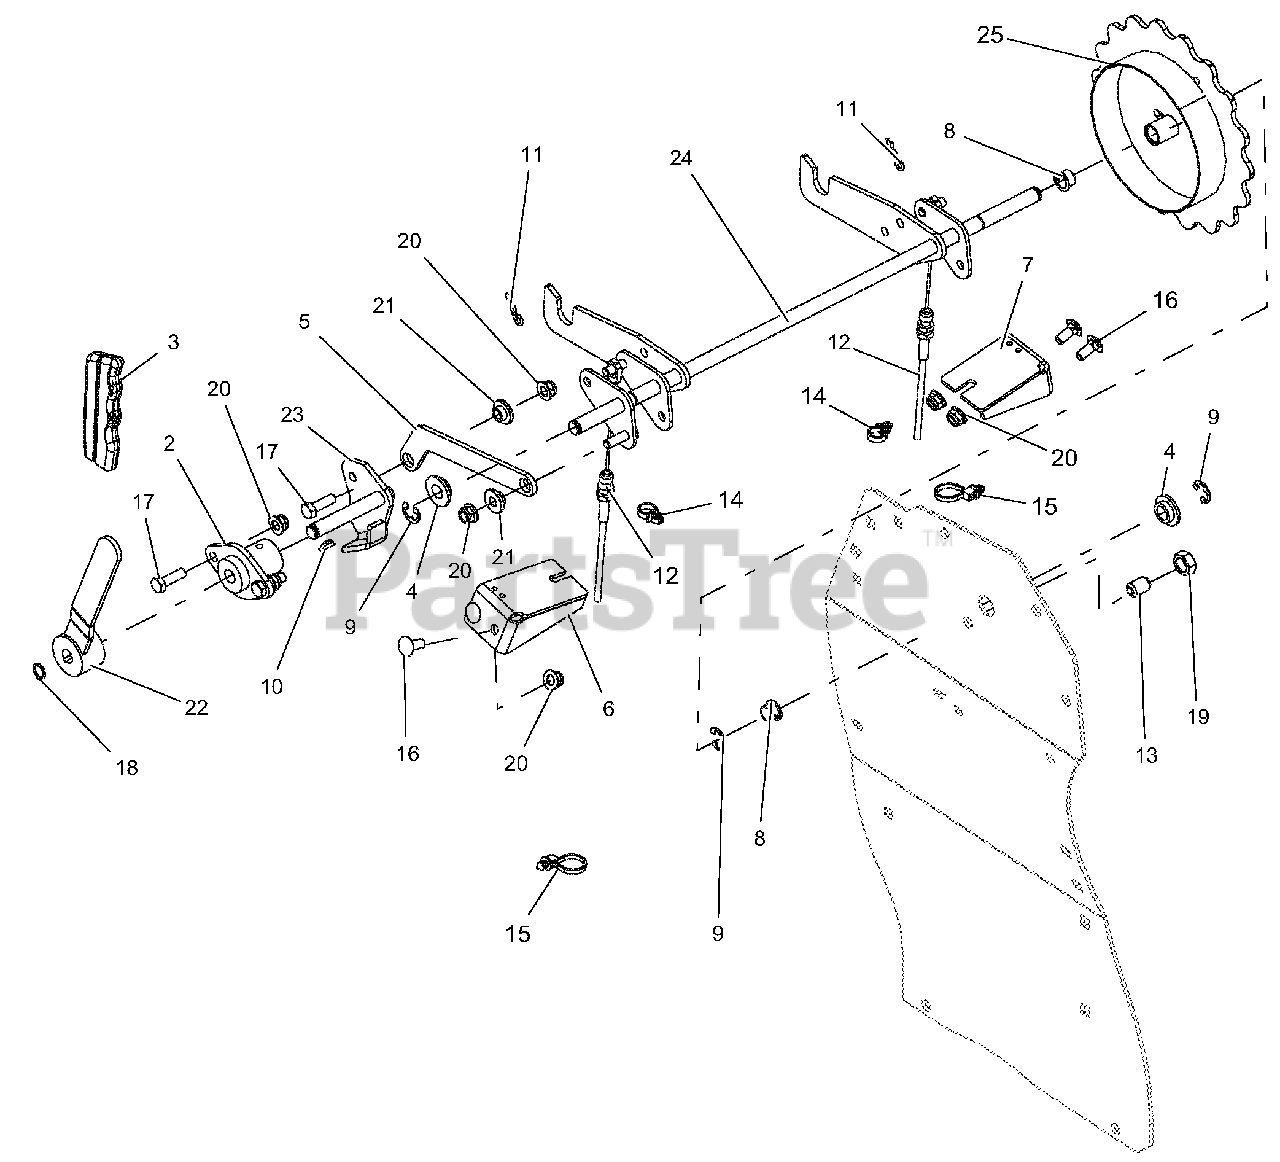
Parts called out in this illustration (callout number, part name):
2	BSHG, FLANGE .500 ID
3	GRIP, PARKING BRAKE (YELLOW )
4	BSHG, FLANGE .515X.750X.31X1.12
5	LINK, INTERLOCK
6	BRKT, CABLE MTG.
7	BRKT, LH CABLE MTG
8	BUSHING, POLYLINER - .50 SPLIT
9	RG-RTNG-EXT .500X.042 (E)
10	KEY, WDRF .13x.63 HRD#5 GM124545 P
11	PIN, HAIR INT .08X.18X1.18 YWZC
12	CABLE, PROSTANCE P. BRAKE
13	BALL SPRING PLUNGER, .500-13
14	CLIP, ROUTING (.50 ID)
15	CABLE TIE W/ TREE (.25 HOLE)
16	BLT-RDHDSQNK .31-18X.75 G5 YWZC
17	BLT-HEX .31-18X1.00 GR5 YWZC
18	RG-RTNG-EXT .500x.050
19	NUT, JAM .500-13 YWZC
20	NUT-LK-NYL-FLG .31-18 YWZC
21	BSHG, FLG .32X.500.344X.880
22	W LDMT, PARKING BRAKE LEVER
23	W LDMT, PARKING BRAKE ACTUATING
24	W LDMT, BRAKE INTERLOCK
25	W LDMT, HEIGHT OF CUT
